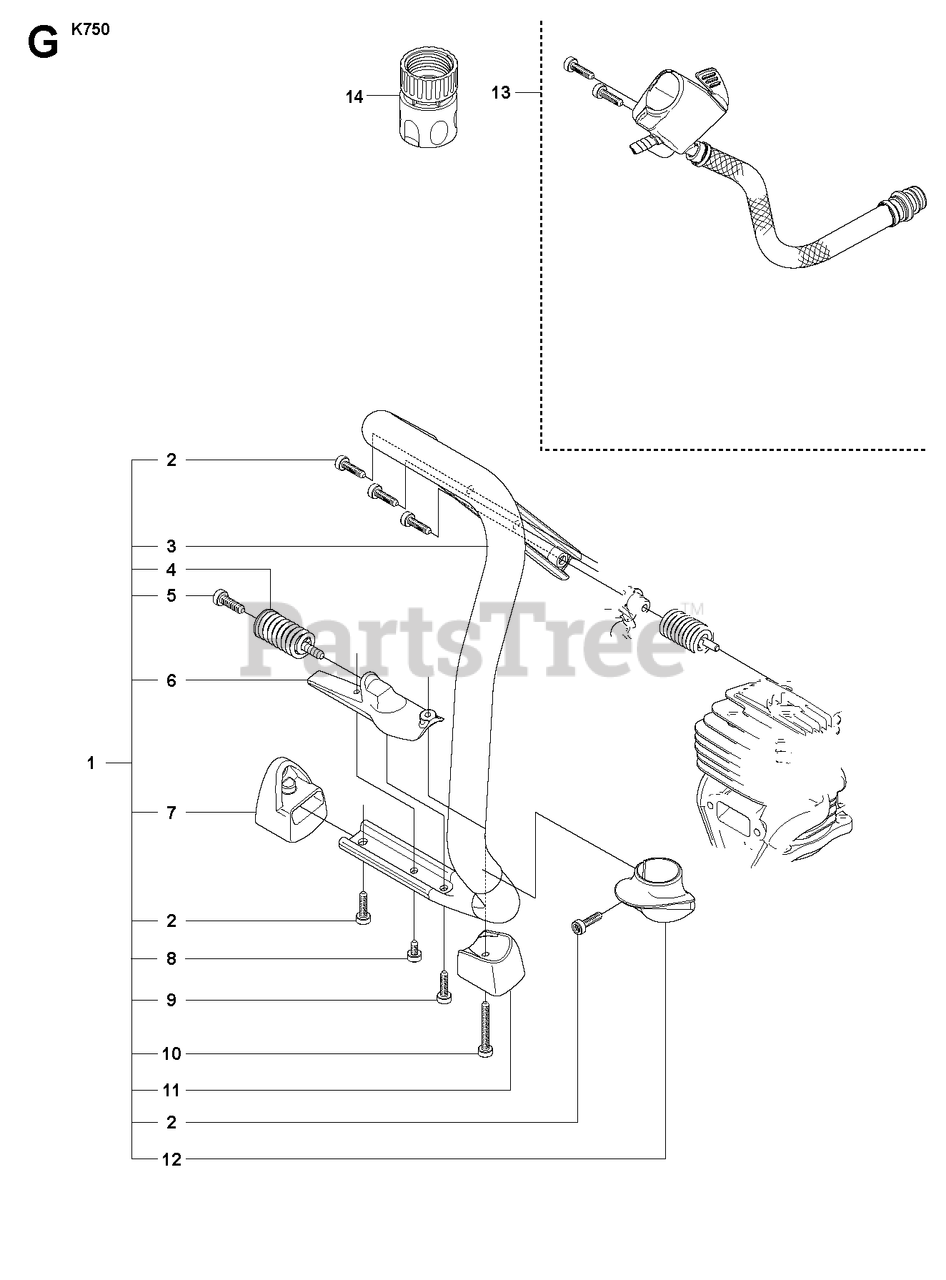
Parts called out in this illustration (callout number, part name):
1	HANDLEIncl. 2 - 12
2	SCREW ITXSCT
3	FRONT HANDLE
4	ANTIVIBRATION ELEMENT
5	SCREW ITXSCM
6	SPRING RETAINER
7	GROUND SUPPORT
8	SCREW ITXSCM
9	SCREW ITXSCM
10	SCREW ITXSCM
11	GROUND SUPPORT
13	HOSE ASSY
14	COUPLER
